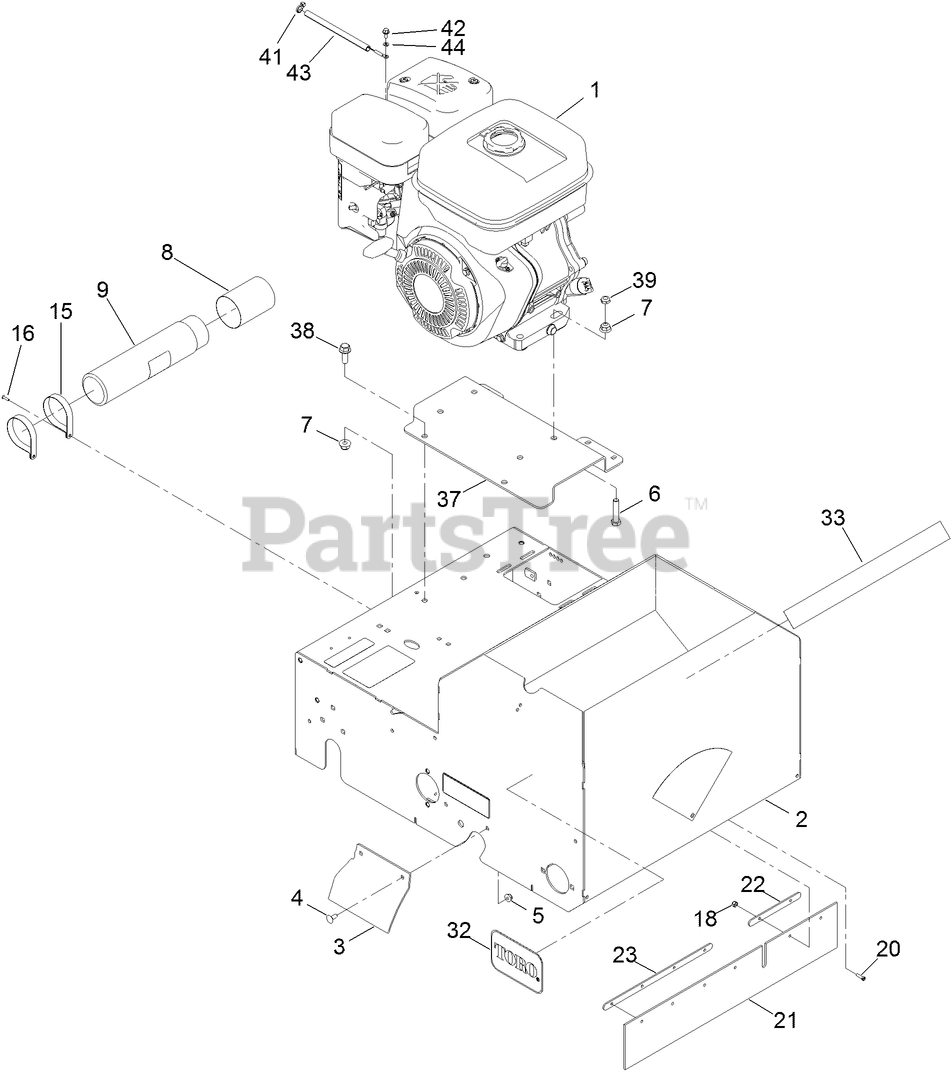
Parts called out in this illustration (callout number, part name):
2	FRAME ASM
3	GUARD-RH
4	SCREW-CARR
5	NUT-HF
6	SCREW-HH
7	NUT-HF, NI
8	CAP-HOUSING
9	TUBE-MANUAL
15	CLAMP-R
16	RIVET-POP
18	NUT-LOCK
20	SCREW-SHH
21	GUARD-DUST
22	PLATE-RETAINER
23	PLATE-RETAINER
32	DECAL
37	PLATE-ENGINE
38	SCREW-HHF
39	NUT-LOCK, NI
41	TIE-CABLE
42	SCREW-HFH
43	RFI-SHEATHING
44	WASHER-LOCK, SPRING
